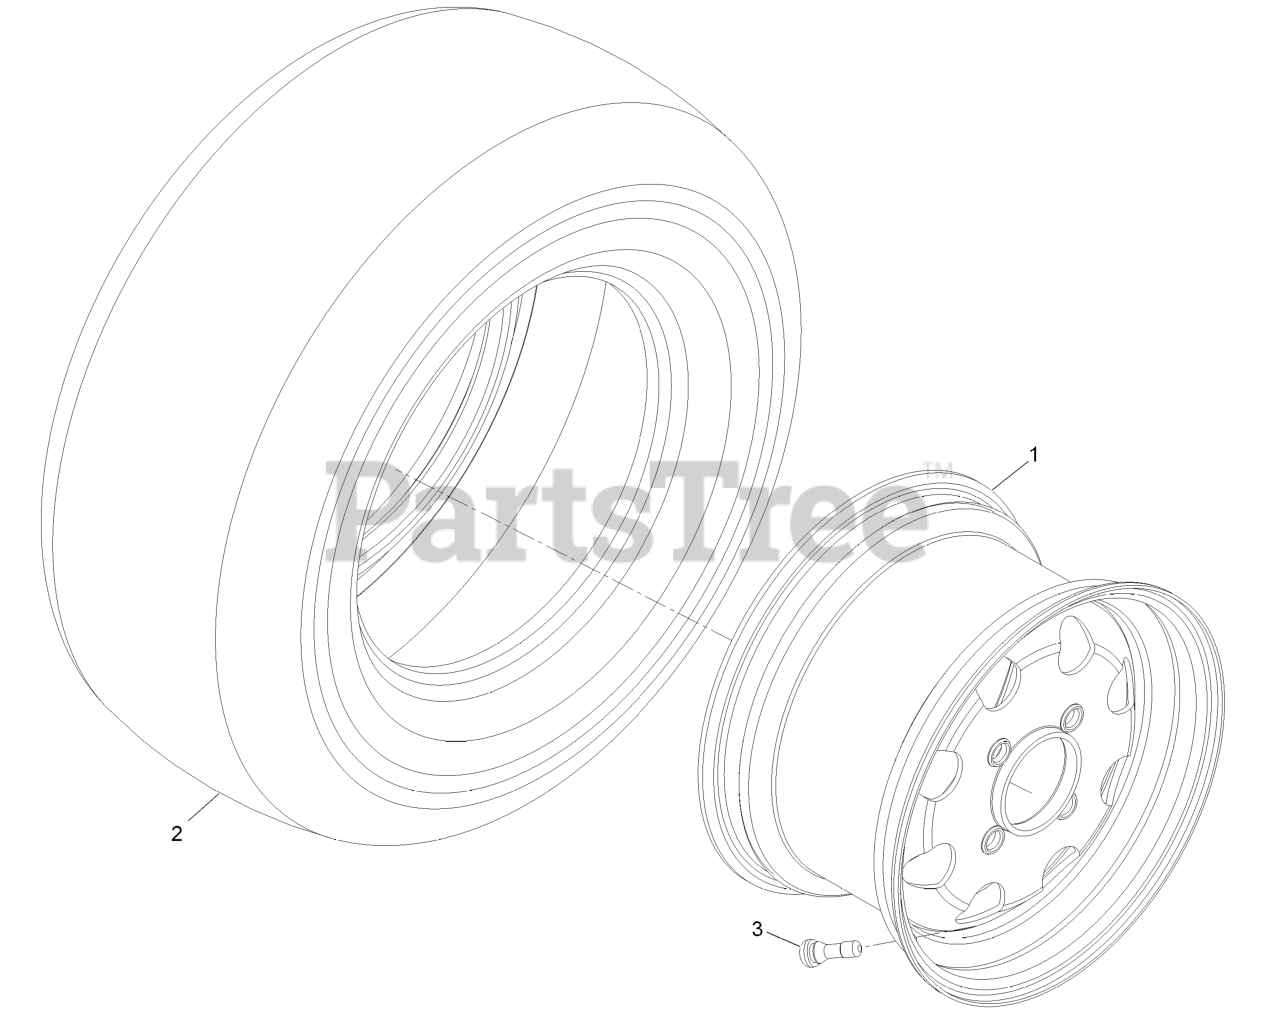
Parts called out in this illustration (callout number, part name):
1	RIM ASM
2	TIRE-STANDARD
3	Stem-Valve
